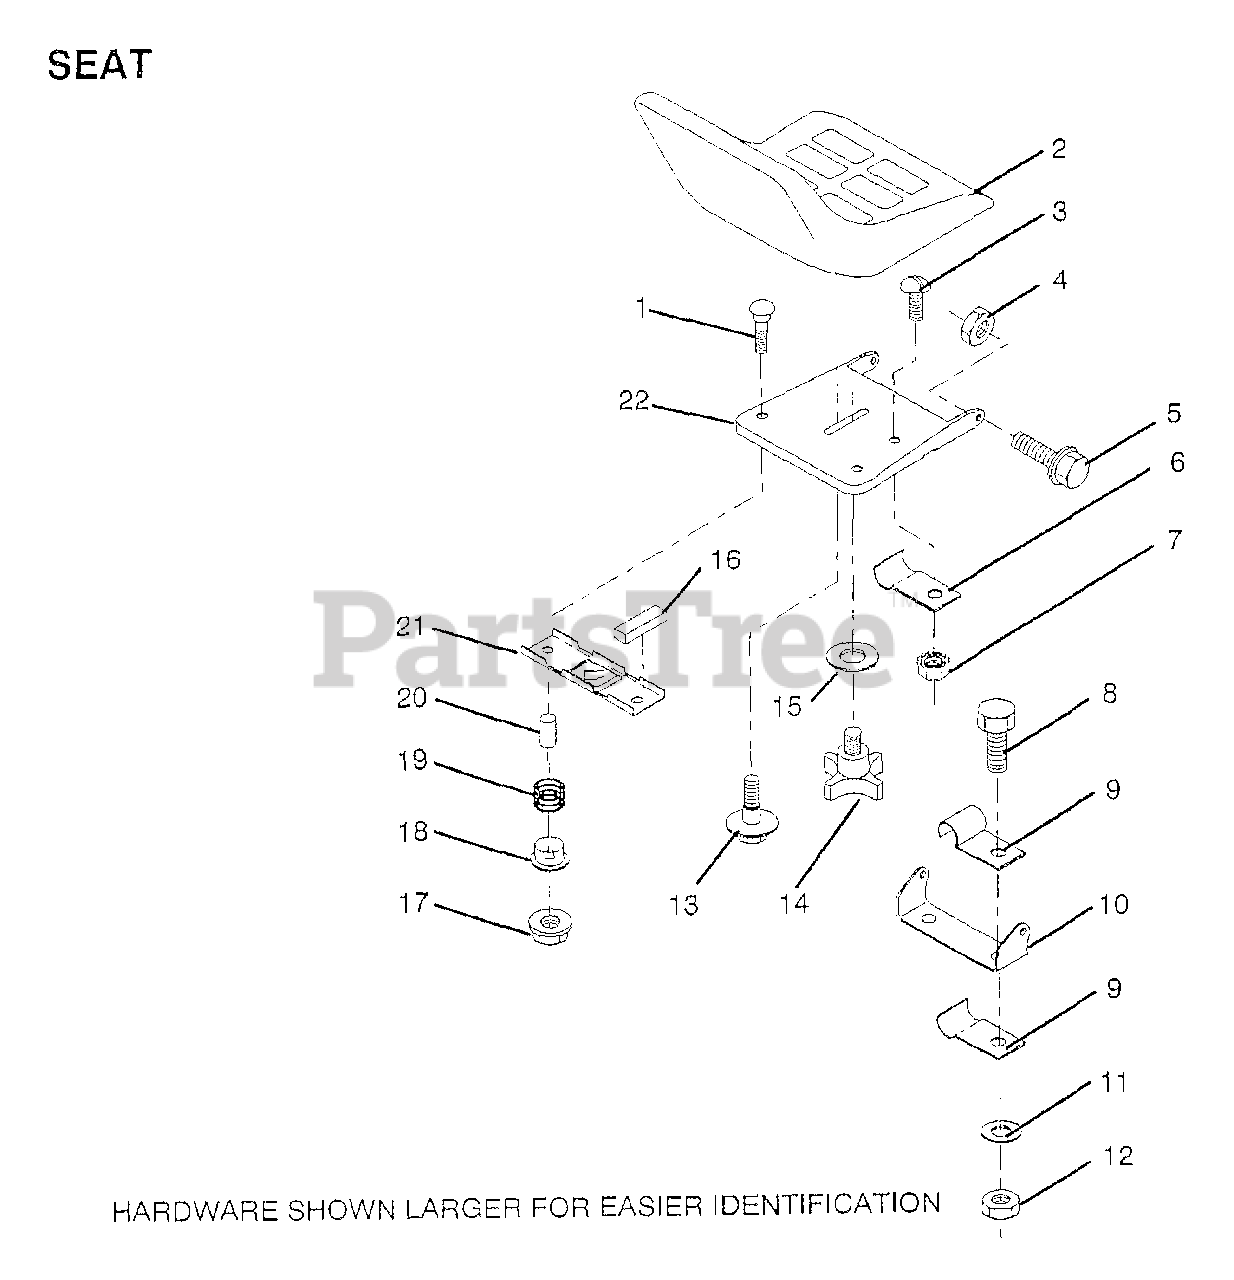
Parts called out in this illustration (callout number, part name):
1	BOLT
7	"NUT,KEPS"
9	"CLIP,INSULATOR"
11	WASHER
13	"BOLT,SHOULDER"
14	"KNOB 1/2"" YT"
15	WASHER
16	STRIP FORM
18	BUSHING
19	SPRING
20	SPACER SPLIT
21	BRKT SWITCH
